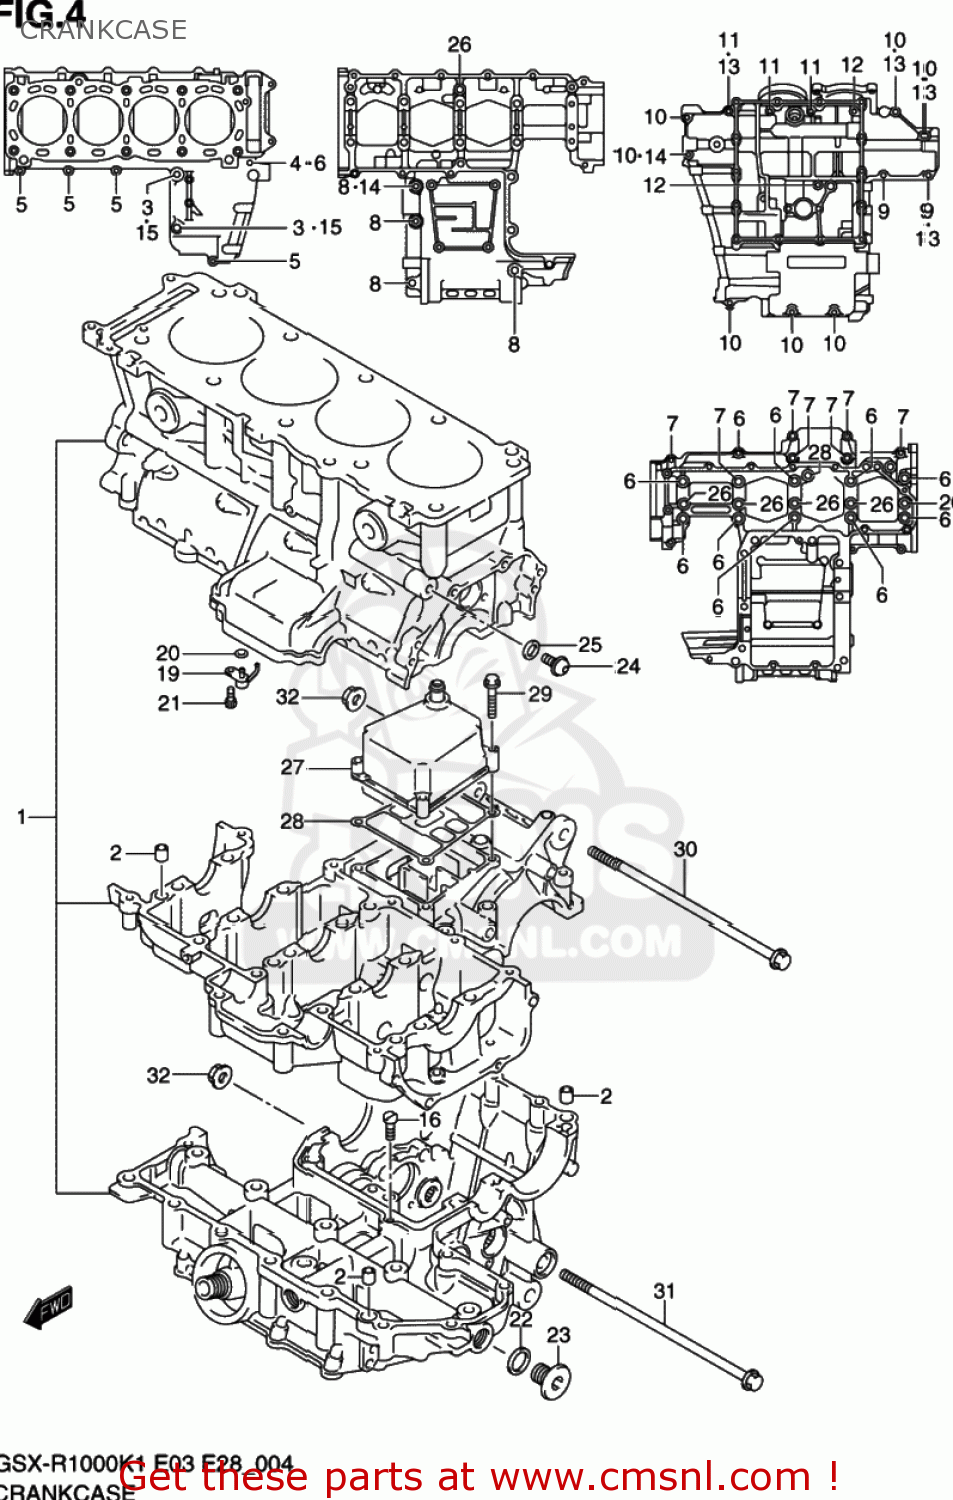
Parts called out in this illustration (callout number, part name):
1	CRANKCASE SET
2	PIN,CRANKCASE
3	BOLT(8X120)
4	GASKET(5.8X13X1.2) (NAS)
5	BOLT
6	BOLT(9X95)
7	BOLT
8	BOLT
9	BOLT,G/S SWITC
10	BOLT
11	BOLT
12	BOLT
13	GASKET(5.8X13X1.2) (NAS)
14	GASKET(8.2X14X1) (NAS)
15	GASKET(8.2X14X1) (NAS)
16	JET(140)
17	BEARING,CRANK THRUST(GREEN)
18	BEARING,CRANK THRUST(RED)
19	JET,PISTON COOLING
20	O RING(D:1.2,ID:4)
21	BOLT(6X12)
22	GASKET(16X22X2) (NAS)
23	PLUG
24	PLUG(10X10)
25	GASKET(10X14X3.6) (NAS)
26	O RING(D:1.9,ID:7.8)
27	COVER,BREATHER
28	GASKET,BREATHER COVER (NAS)
29	BOLT
30	BOLT 10X215
31	BOLT 10X215
32	NUT
